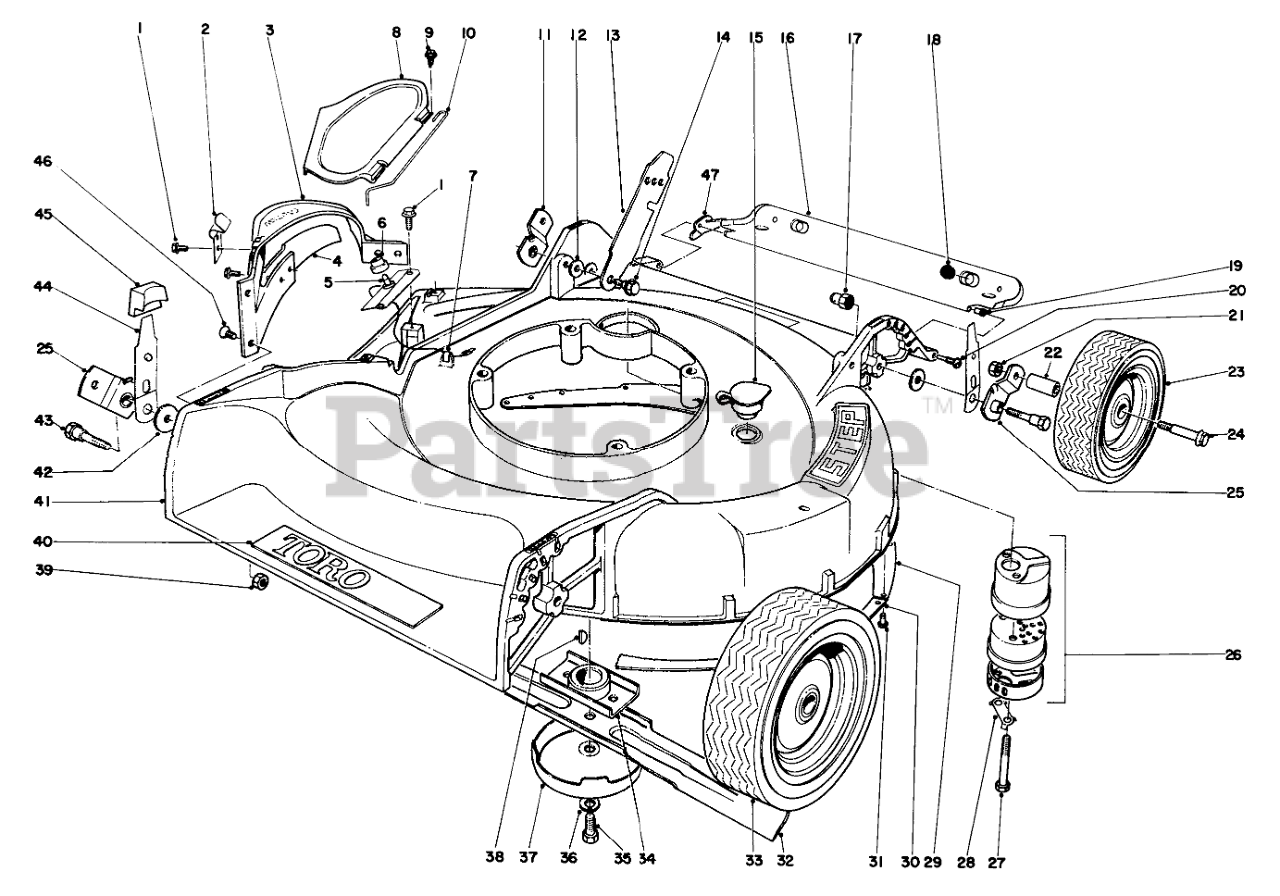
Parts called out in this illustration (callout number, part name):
2	Latch
3	Deflector (Incl. Ref. #1, 2&4)
4	DefIector Bar
5	Deflector Switch & Wire (Incl. Ref. #6)
6	Boot Switch
8	Deflector Cover
9	SCREW
10	Hinge Spring
11	Pivot Arm
12	SPACER
13	Latch
14	SCREW-SHOULDER
15	WASHOUT PLUG
16	Rear Safety Shield (Incl. Ref. #18 & 19)
17	HANDLE PIVOT NUT
18	SKID BUTTON
19	SAFTEY SHIELD BUSHING
20	SAFTEY SHIELD SCREW
21	Nut
22	Bushing
23	Wheel Assembly
25	Pivot Arm
26	Muffler (Incl. Ref. #27 & 28)
27	SCREW-HH
28	CLIP - LOCKING
29	Main Skirt
30	Secondary Skirt
32	Blade
33	Wheel Assembly
34	BLADE RETAINER WA
35	SPECIAL SCREW
36	WASHER-LOCK
37	AntiScalp Cup
38	KEY-WOODRUFF
39	Nut
40	Toro Emblem
41	Housing (Incl. Ref. #29, 30 & 31)
42	WASHER-PIVOT
43	5/16-18 PIVOT SCREW
44	Spring Arm
45	Knob
46	Screw
47	Restraint R.H.
